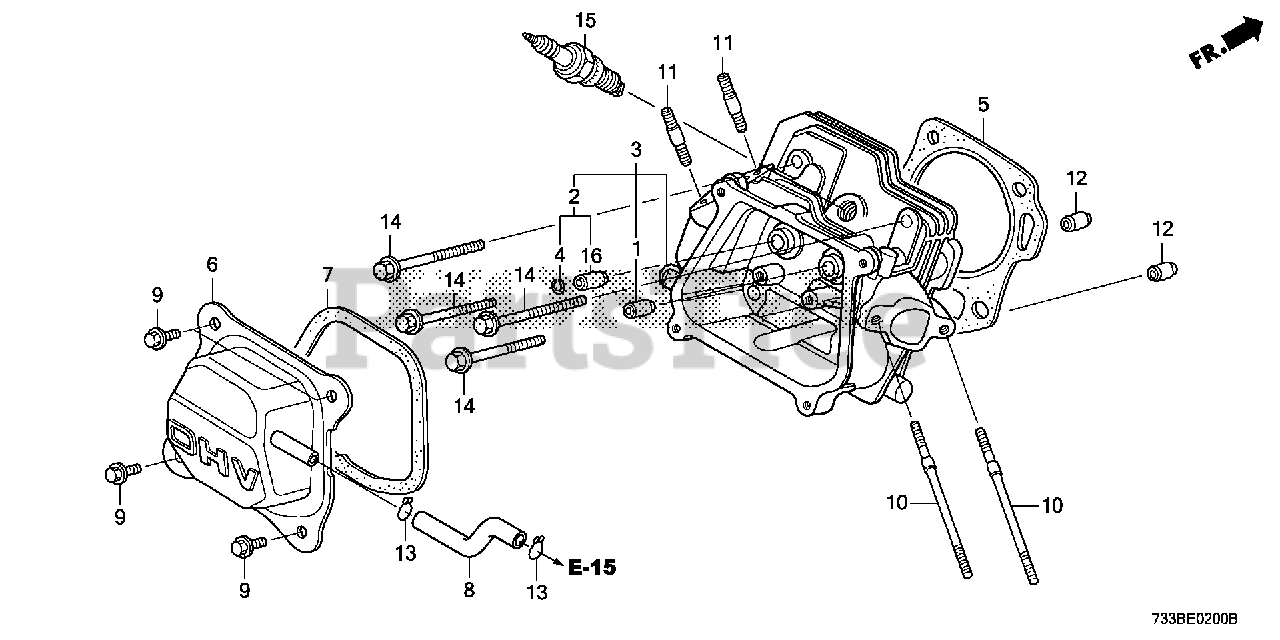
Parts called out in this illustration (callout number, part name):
1	GUIDE, VALVE (OVER SIZE) Use from Engine SN 6324986.
2	GUIDE, EX. VALVE (OS)
3	CYLINDER HEAD
4	CLIP, VALVE GUIDE Use from Engine SN 1231803.
5	GASKET, CYLINDER HEAD (NIPPON LEAKLESS)
6	COVER, HEAD
7	GASKET, CYLINDER HEAD COVER
7	GASKET, HEAD COVER (NINGBO SIL GASKET)
8	TUBE, BREATHER
9	BOLT, FLANGE (6X12) (CT200)
10	BOLT, STUD (6X112)
11	BOLT, STUD (8X32)
12	PIN A, DOWEL (10X16)
13	CLIP, TUBE (C12)
14	BOLT, FLANGE (8X60)
15	SPARK PLUG (BPR5ES) (NGK)
15	SPARK PLUG (W16EPR-U) (DENSO)
15	SPARK PLUG (BPR6ES) (NGK)
15	SPARK PLUG (W20EPR-U) (DENSO)
16	GUIDE, EX. VALVE (OVER SIZE)
